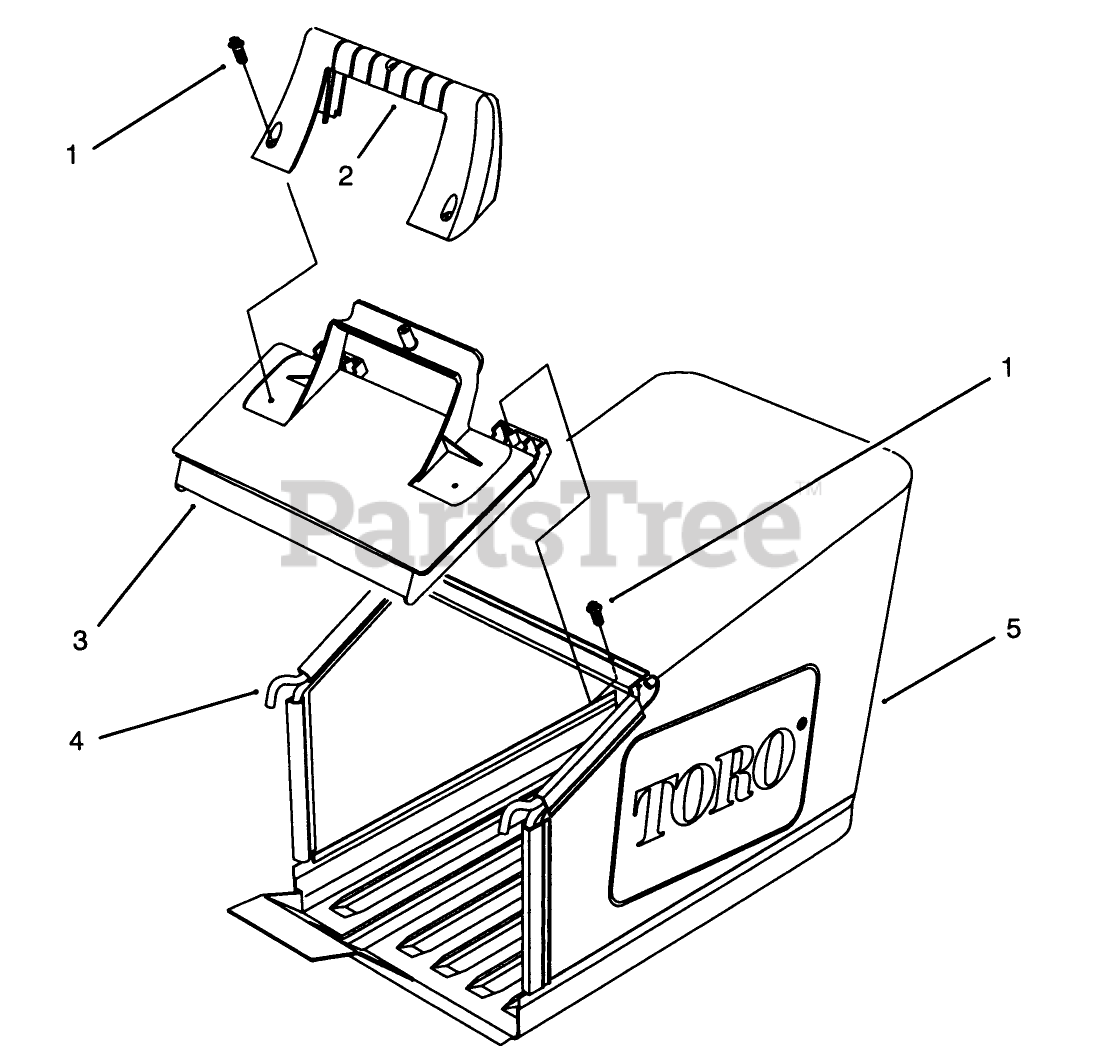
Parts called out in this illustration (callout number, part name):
1	SCREW-THD ROLL, HWH
2	HANDLE-DOOR
3	DOOR-BAG
5	GRASS BAG 48CM W/PAN
